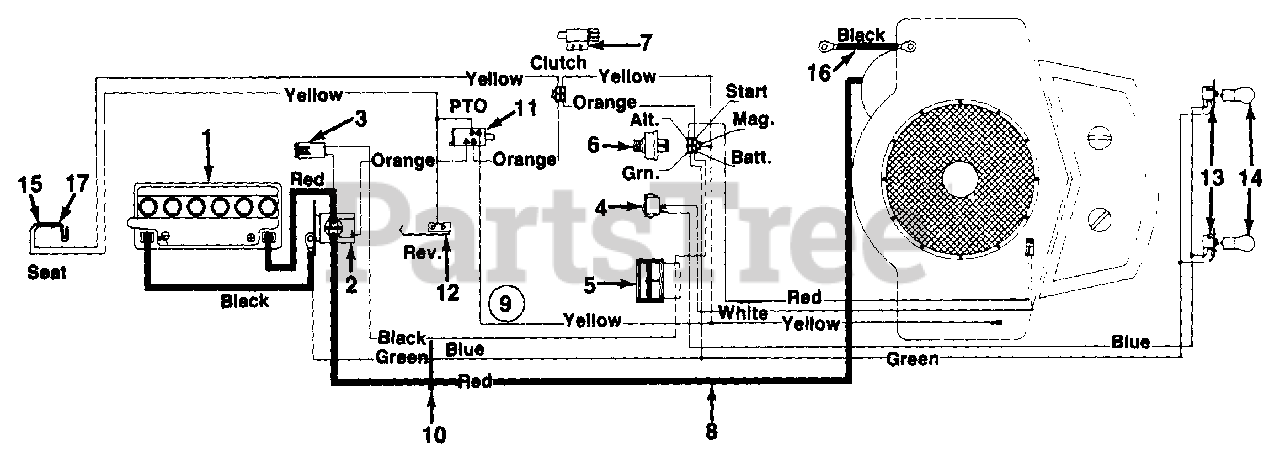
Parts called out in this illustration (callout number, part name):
1	Battery (275 Cold Crank Amps)
2	Solenoid
3	Fuse 7.5 Amps
4	Light Switch
5	Ammeter
6	Ignition Switch
7	Safety Switch (Clutch)
8	Electric Wire 32.5" Lg. (B&S)
9	Wire Harness w/o Ammeter
10	Cable Tie
11	Safety Switch (Deck)
12	Safety Switch (Reverse)
13	Socket
14	Bulb (Headlight)
15	Safety Switch (Seat)
16	Ground Wire 7.5" Lg.
17	Safety Switch (Seat)
